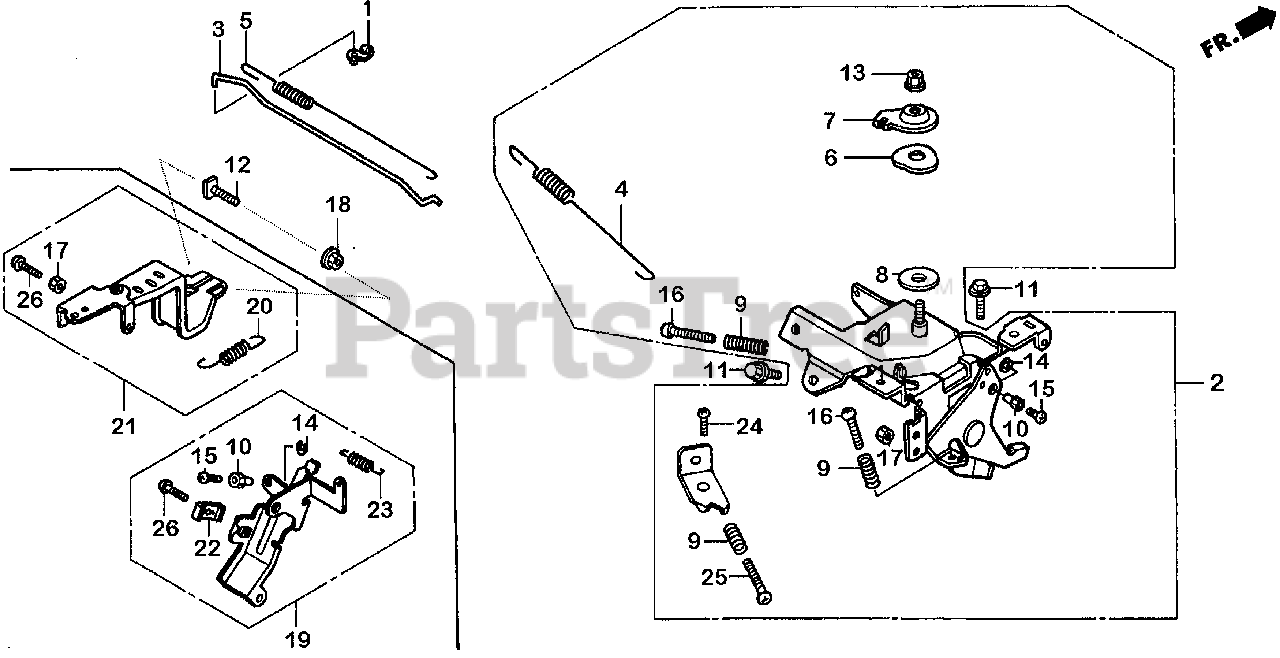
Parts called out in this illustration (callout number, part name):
1	JOINT, ROD
2	CONTROL ASSY. (SEC)
3	ROD, GOVERNOR
4	SPRING, GOVERNOR
5	SPRING, THROTTLE RETURN
6	SPRING, LEVER
7	WASHER, CONTROL LEVER
8	SPACER, CONTROL LEVER
9	SPRING, CONTROL ADJUSTING Use from Engine SN 2327377.
10	HOLDER, WIRE
11	BOLT, FLANGE (6X12) (CT200)
12	BOLT, GOVERNOR ARM
13	NUT, SELF-LOCK (6MM)
14	CIRCLIP (5MM) Use from Engine SN 2327377.
15	SCREW, PAN (4X6)
16	SCREW, PAN (5X25)
17	NUT, HEX. (5MM)
18	NUT, FLANGE (6MM)
19	STAY ASSY., AUTO THROTTLE
19	STAY ASSY., AUTO THROTTLE (SEC)
20	SPRING, RETURN
21	ARM, GOVERNOR (NOT AVAILABLE)
22	HOLDER, CABLE
23	SPRING, CABLE RETURN
24	SCREW, PAN (5X12)
25	SCREW, PAN (5X28)
26	SCREW, PAN (5X16)
